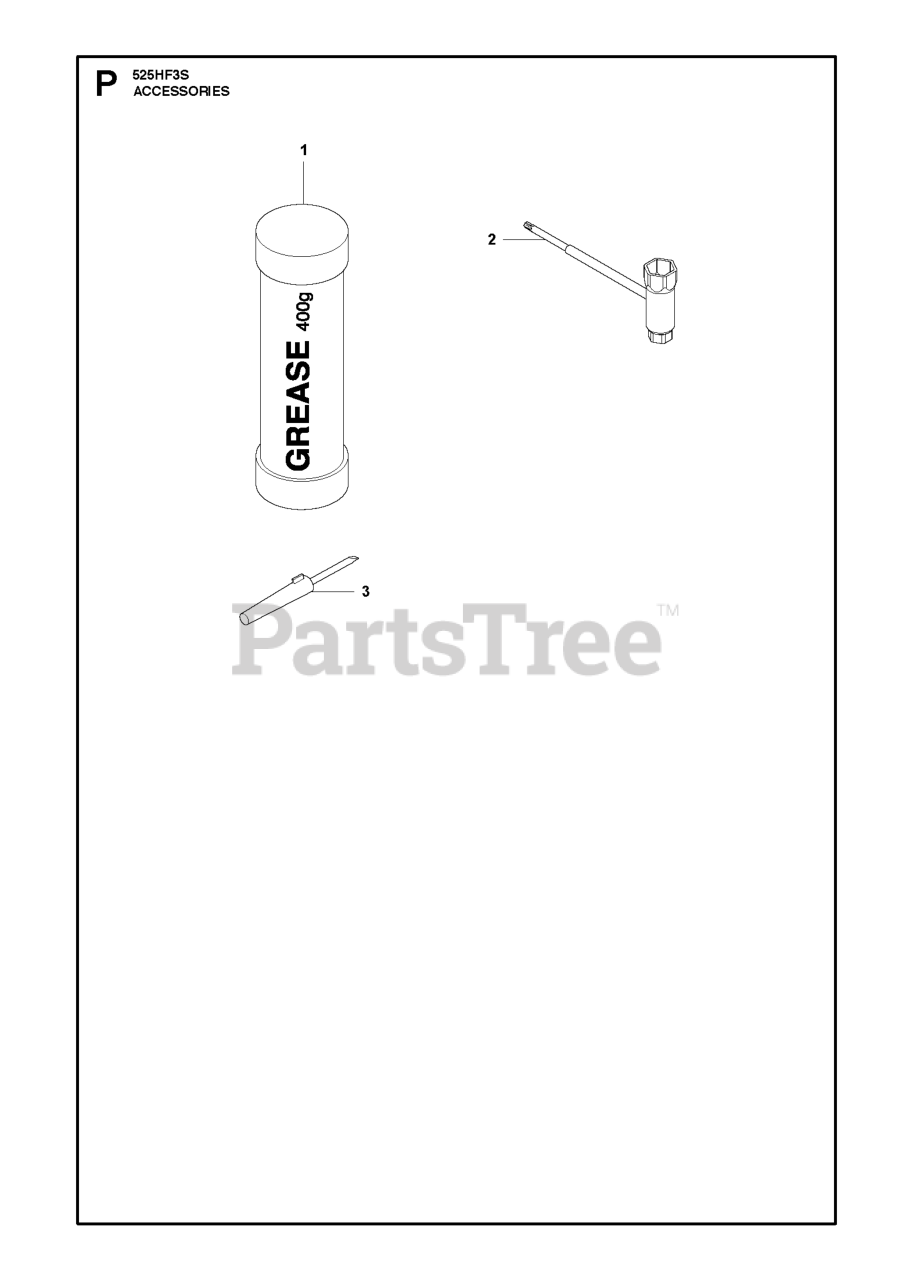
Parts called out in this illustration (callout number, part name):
1	HUS MULTI ADVANCE GREASE 400GR
2	COMBINATION WRENCH TORX
3	SCREWDRIVER
